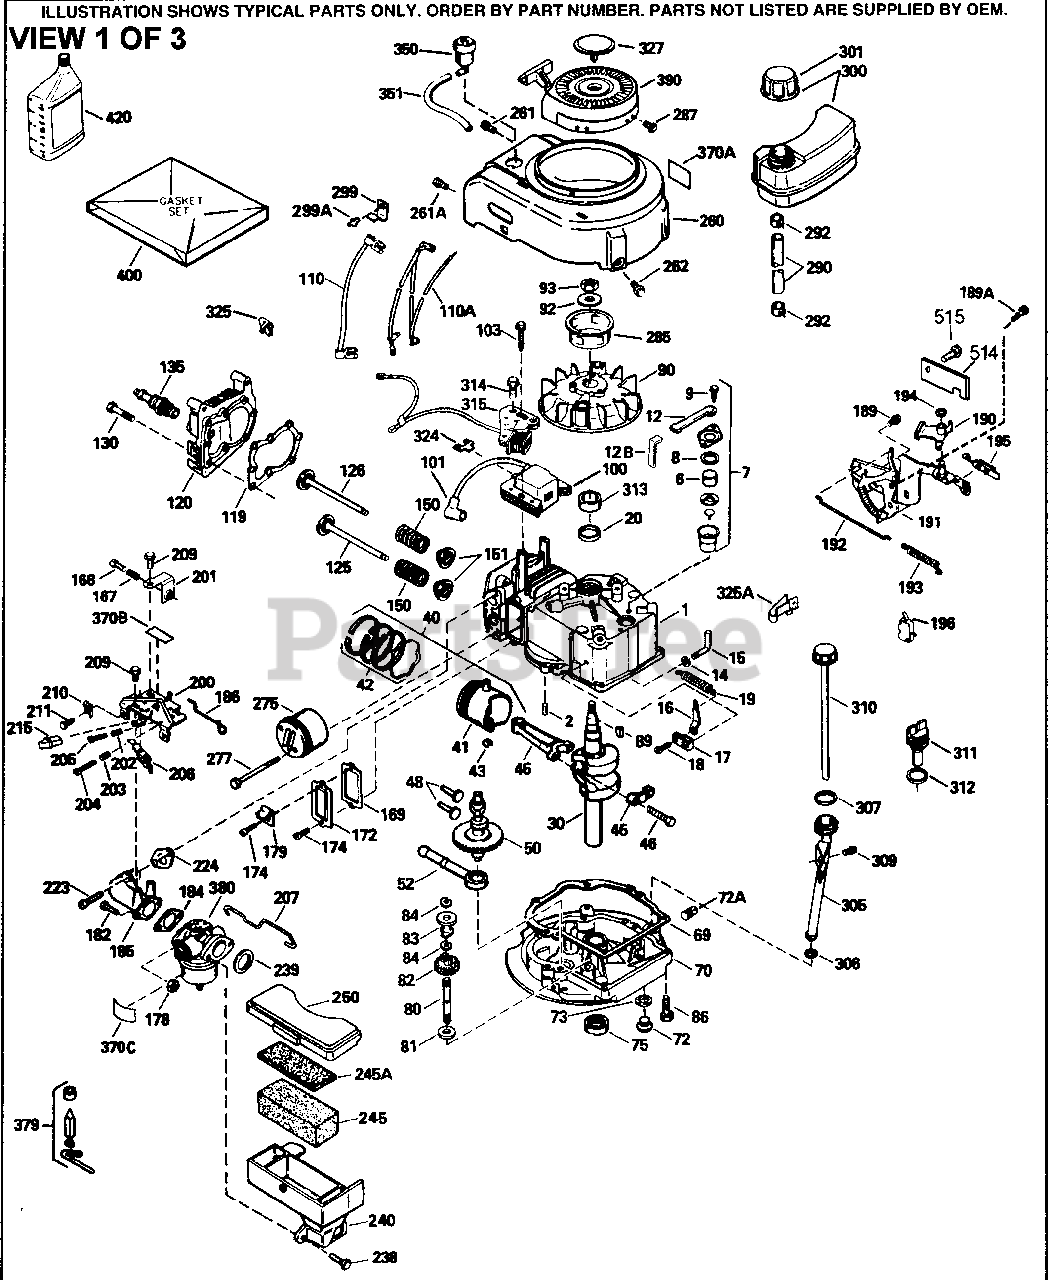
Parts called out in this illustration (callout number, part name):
1	"Cylinder (Incl. 2 & 20)
2	Dowel Pin
6	Breather Element
7	Breather Ass'y. (Incl. 6, 8, 9 & 12)
8	* Breather Gasket
9	Screw, 10-24 x 9/16"
12	Breather Tube
14	Flat Washer
15	Governor Rod (Incl. 14)
16	Governor Lever
17	Governor Lever Clamp
18	Screw, 8-32 x 5/16"
19	Extension Spring
20	Oil Seal
30	Crankshaft
40	Piston, Pin & Ring Set (Std.) (2-5/8"
40	Piston, Pin & Ring Set (.010" OS)
40	Piston, Pin & Ring Set (.020" OS) (In cl. 41, 42 & 43)
41	Piston & Pin Assembly (Std.) (Incl. 4 3)
41	Piston & Pin Assembly (.010" OS) (Inc l. 43)
41	Piston & Pin Assembly (.020" OS) (Inc l. 43)
42	Ring Set (Std.) (2-5/8" Bore)
42	Ring Set (.010" OS)
42	Ring Set (.020" OS)
43	Piston Pin Retaining Ring
45	Connecting Rod Ass'y. (Incl. 46)
46	Connecting Rod Bolt
48	Valve Lifter
50	Camshaft
52	Oil Pump Ass'y.
69	* Mounting Flange Gasket
70	Mounting Flange (Incl. 72, 75, & 80)
72	Oil Drain Plug
73	Drain Plug Gasket
75	Oil Seal
80	Governor Shaft
82	Governor Gear Ass'y. (Incl. 81)
83	Governor Spool
84	Retaining Ring
86	Screw, 1/4-20 x 1-1/4"
89	Flywheel Key (also available in Packa ged Part #740007B)
90	Flywheel
92	Belleville Washer
93	Flywheel Nut
100	Solid State Ignition
101	Spark Plug Cover
103	Screw, Torx T-15, 10-24 x 1"
110	Ground Wire
119	* Cylinder Head Gasket
120	Cylinder Head
125	Exhaust Valve (Std.) (Incl. 151)
125	Exhaust Valve (1/32" OS) (Incl. 151)
126	Intake Valve (Std.) (Incl. 151)
126	Exhaust Valve (1/32" OS) (Incl. 151)
130	Screw, 5/16-18 x 1-1/2"
135	Resistor Spark Plug (RJ19LM) also ava ilable in Packaged Part #740081
150	Valve Spring
151	Valve Spring Keeper
169	* Valve Cover Gasket
172	Valve Cover
174	Screw, 10-24 x 1/2"
178	Nut & Lock Washer 1/4-28
182	Screw, 1/4-28 x 7/8"
184	* Carburetor To Intake Pipe Gasket
185	Intake Pipe (Incl. 224)
186	Governor Link
200	Control Bracket (Incl. 202 thru 205)
202	Compression Spring
203	Compression Spring
204	Screw, 5-40 x 7/16"
205	Screw, 6-32 x 21/32"
206	Terminal
207	Throttle Link
209	Screw, 10-24 x 9/16"
215	Control Knob
223	Screw, 1/4-20 x 1"
224	* Intake Pipe Gasket
238	Screw, 10-32 x 49/64"
239	* Air Cleaner Gasket
250	Air Filter Cover (Craftsman)
260	Blower Housing
261	Screw, 10-24 x 9/16"
262	Screw, 1/4-20 x 1/2"
275	Muffler (Incl. 277)
277	Screw, 1/4-20 x 2-1/4"
285	Starter Cup
287	Screw, 8-32 x 1/2"
290	Fuel Line
292	Fuel Line Clamp
300	Fuel Tank (Incl. 292 & 301)
301	Fuel Cap (Red)
305	Oil Fill Tube
306	Fill Tube Gasket
307	"O" Ring
309	Screw, 10-32 x 1/2"
310	Dipstick
327	Starter Plug
380	Carburetor (Incl.184)
390	Rewind Starter
400	Gasket Set (Incl. items marked PK in notes) Incl. (1) each of the followi ng: 26754A, 26756, 27234A, 27272A, 28 833, 29673, 29953C, 30081A, 31619A,31 688A, 32643A, 32649A, 32752A, 32760A, 33015A, 33051, 33670A, 33735,34338, 34690A, 35261, 35815
999	Summer Maintenance Kit (incl. Oil, Sp ark Plug, Air Cleaners (2), & Ultra-F resh)
